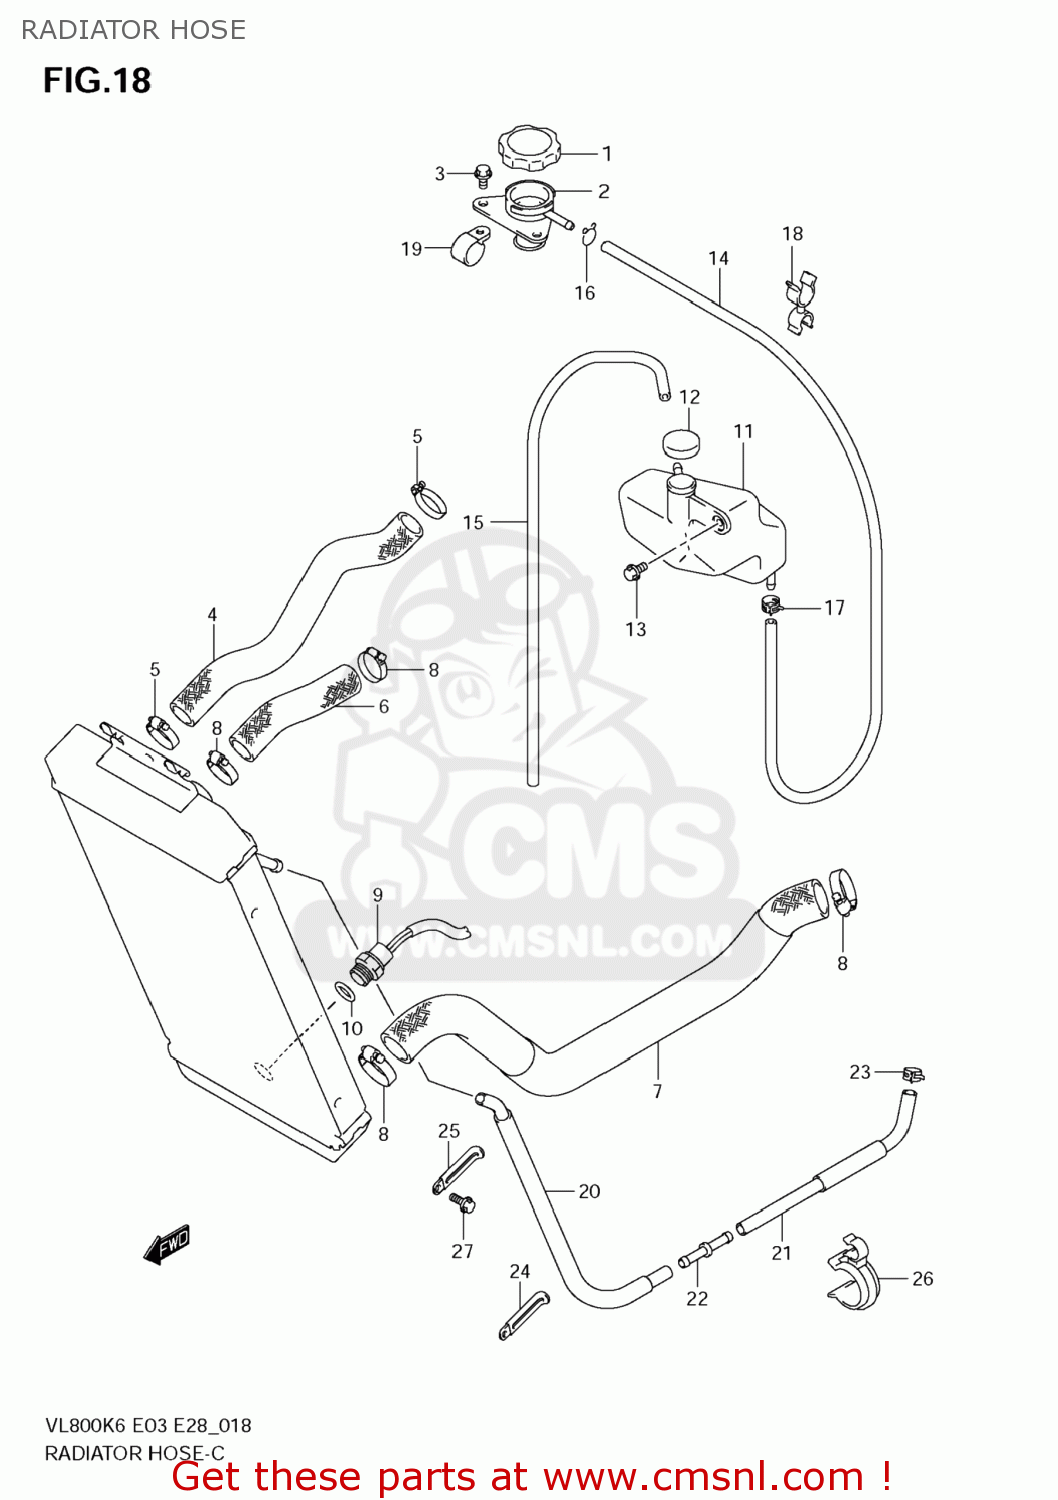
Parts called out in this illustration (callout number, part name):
1	CAP,RADIATOR
2	CONDUCTION,RADIATOR
3	BOLT
4	HOSE,CONDUCTION
5	CLAMP
6	HOSE,RADIATOR INLET
7	HOSE,RADIATOR OUTLET
8	CLAMP
9	SWITCH,RADIATOR FAN
10	O-RING
11	TANK,RESERVOIR
12	CAP,RESERVOIR TANK
13	BOLT(6X12)
14	HOSE,RSVR INLE
15	HOSE,RESERVOIR TANK INLET
16	CLIP
17	CLIP
18	CLAMP
19	CLAMP
20	HOSE,WATER BYPASS
21	HOSE,WATER BYPASS
22	JOINT
23	CLIP
24	CLAMP(L:80)
25	CLAMP(L:82)
26	CLAMP
27	BOLT(10X16)
